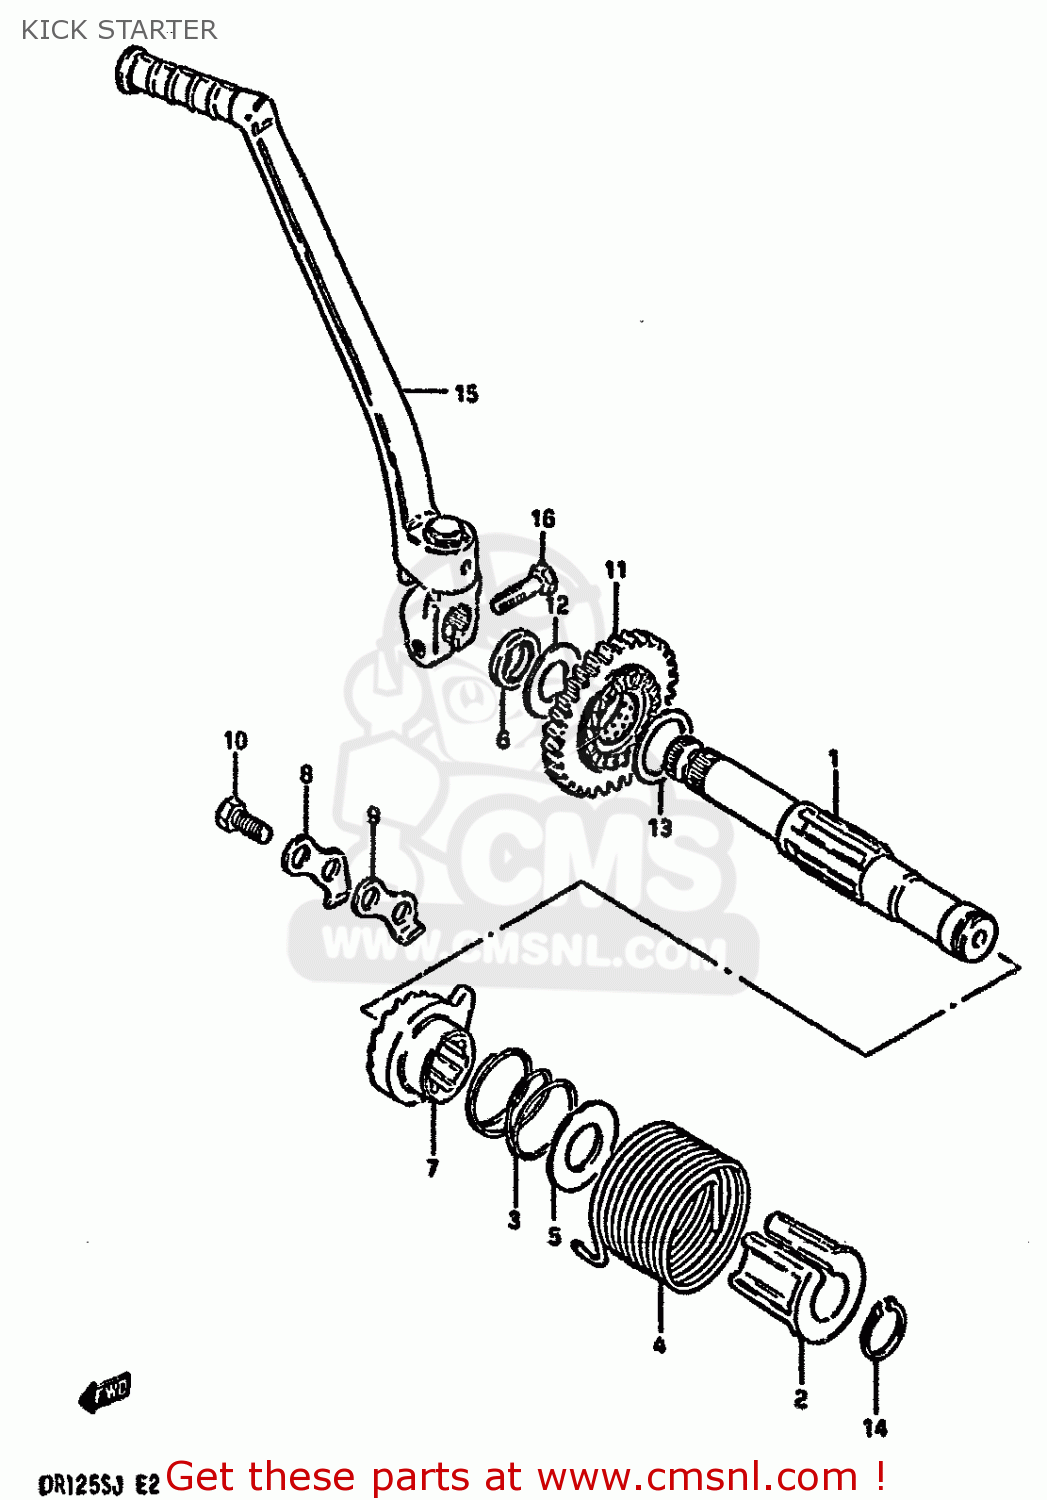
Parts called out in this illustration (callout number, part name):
1	SHAFT,KICK STARTER
2	GUIDE,KICK STARTER SFT SPRING
3	SPRING
4	SPRING
5	WASHER
6	SEAL,OIL(16X24X5)
7	STARTER,KICK
8	GUIDE,KICK STARTER
9	STOPPER,KICK STARTER
10	BOLT
11	GEAR,KICK STARTER DRIVE
12	WASHER(16X30X1)
13	WASHER
14	CIRCLIP
15	LEVER ASSY,KICK STARTER
16	BOLT 8X25
